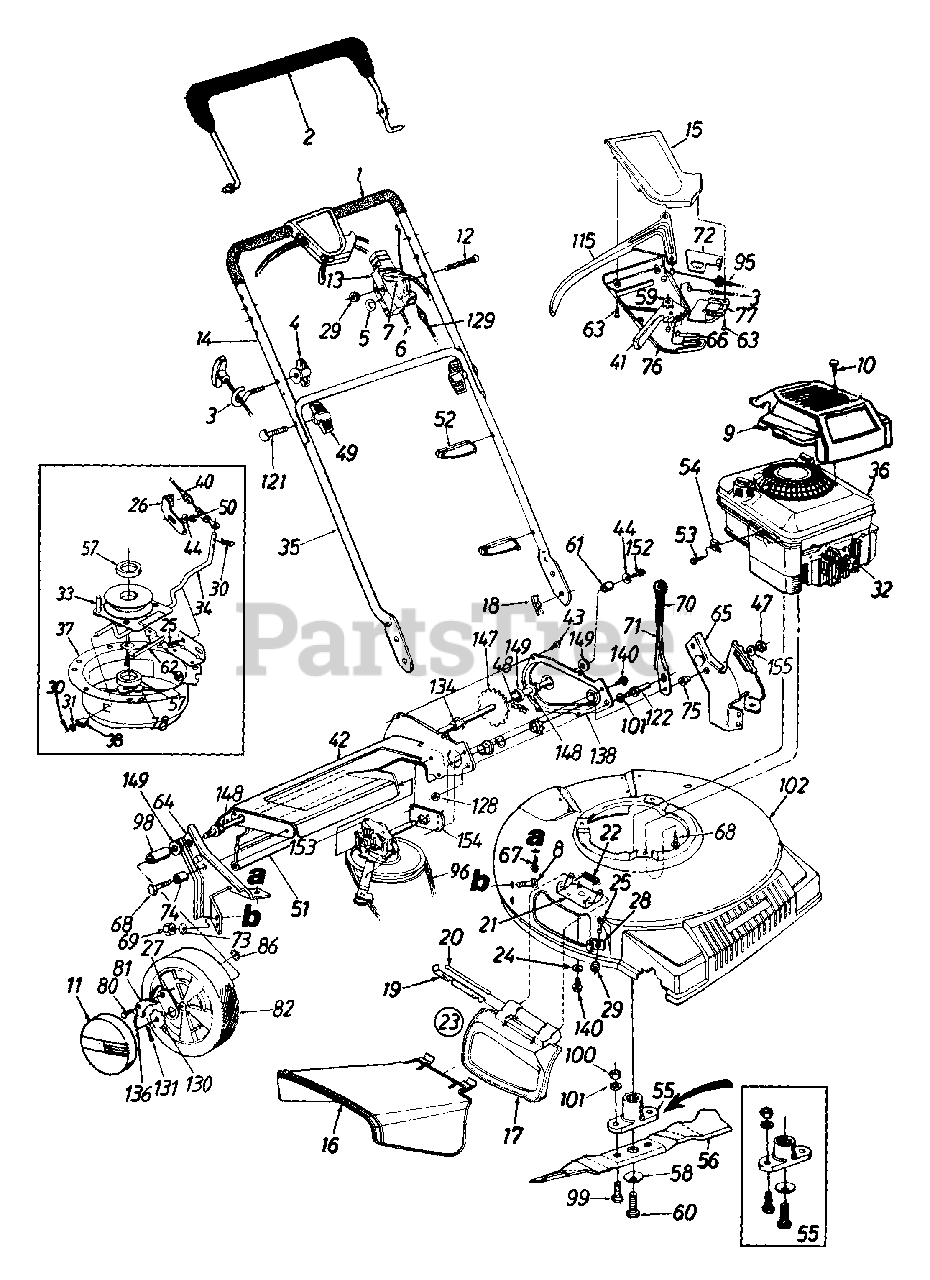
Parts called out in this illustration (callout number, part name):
1	Foam Grip
2	Control Handle
4	Handle Knob 1/4-20 Thd.
5	Curved Spring Wash. .66" I.D.
6	Throttle Wire - 55" Lg.
7	Throttle Lever
8	Carriage Bolt 5/16-18 x .62" Lg.
9	XTE Engine Shroud
10	Hi-Lo Screw #10 x 1.25" Lg.
11	Hub Cap
12	Oval C-Sunk Mach. Ser.
13	Throttle Body
15	Upper Control Housing
16	Side Chute Deflector
17	Mulch Plug
18	Internal Cotter Pin 5/16" Dia.
20	Hinge Pin
22	Torsion Spring
23	Mulch Plug Ass'y. Comp.
24	Bell-Wash. .265" I.D. x .75" O.D.
25	Carriage Bolt 1/4-20 x .5" Lg.
30	Cotter Pin 3/32" Dia. x .75"
31	Fl-Wash. .328" I.D. x .68"
32	Spark Plug Insulator
33	Pulley Ass'y.
34	Shift Rod
36	Engine - 5.5 H.P.
40	6 Spd. Cable
41	6 Spd. Shift Lever
44	Bell-Wash. 1/4" I.D.
47	Hex Patch L-Nut 3/8-24 Thd.
48	#48 Chain .500" Pitch x 38 Links
49	Hand Knob
50	Hex L-Nut 1/4-20 Thd.
51	Rear Flap 4.8" x 17.5" Lg.
52	Cable Tie
53	Hex Wash. Hd. Scr. #10-32 x .62" Lg.
54	Casing Clamp
55	Blade Adapter Kit
56	21" Mulching Blade
57	Spacer .885" I.D. x 1" O.D.
58	Bell-Wash. .39" I.D. x 1.14" O.D.
59	Gear Insert
60	Hex Bolt 3/8-24 x 2.5" Lg. (Gr. 8)
61	Spacer .513" J.D.
67	Hex 8-Tap Scr. 5/16-18
68	Hex TT-Tap Scr. 3/8-16
69	Hex Nut 5/16-18 Thd.
71	Height Adj. Lever
72	6 Spd. Rack Cable Brkt.
73	Bell-Wash. 5/16" I.D.
74	Spacer .383" I.D.
75	Shld. Spacer .5" Dia.
76	Lower Control Housing
77	Cable Mounting Cap
78	Wave Wash. .88" I.D. x 1.38" O.D.
80	Shld. Scr. .342" Dia. x .268
81	Pawl - R.H.
82	Wheel Ass'y. Comp.
86	Weld Top L-Nut 1/4-20 Thd.
95	S.P. Cable
96	"V"-Belt
98	Sleeve .526" I.D.
99	Hex Bolt 3/8-24 x 1.0" Lg.
100	Hex Nut 3/8-24 Thd.
101	L-Wash. 3/8" I.D.
121	Curved Hd. Bolt 5/16-18 x 2" Lg.
122	Shld. Pin 1.43" Lg.
128	Hex Jam Nut 3/8-24 Thd.
129	Control Cable - 39"
130	Ratchet Wheel 1.62" O.D.
131	Cotter Pin 1/8" Dia. x 1"
134	Hex Flange Bearing
136	Spring - Nylon
147	Rear Shaft Ass'y. 21.44" Lg.
148	Hex Flange Brg. .506" I.D.
149	Fl-Wash. .531" I.D. x .930"
152	Hex Bolt 1/4-20 x .62" Lg. (Gr. 5)
153	Transmission Comp.
155	Fl-Wash. .385" I.D. x .87" O.D.
